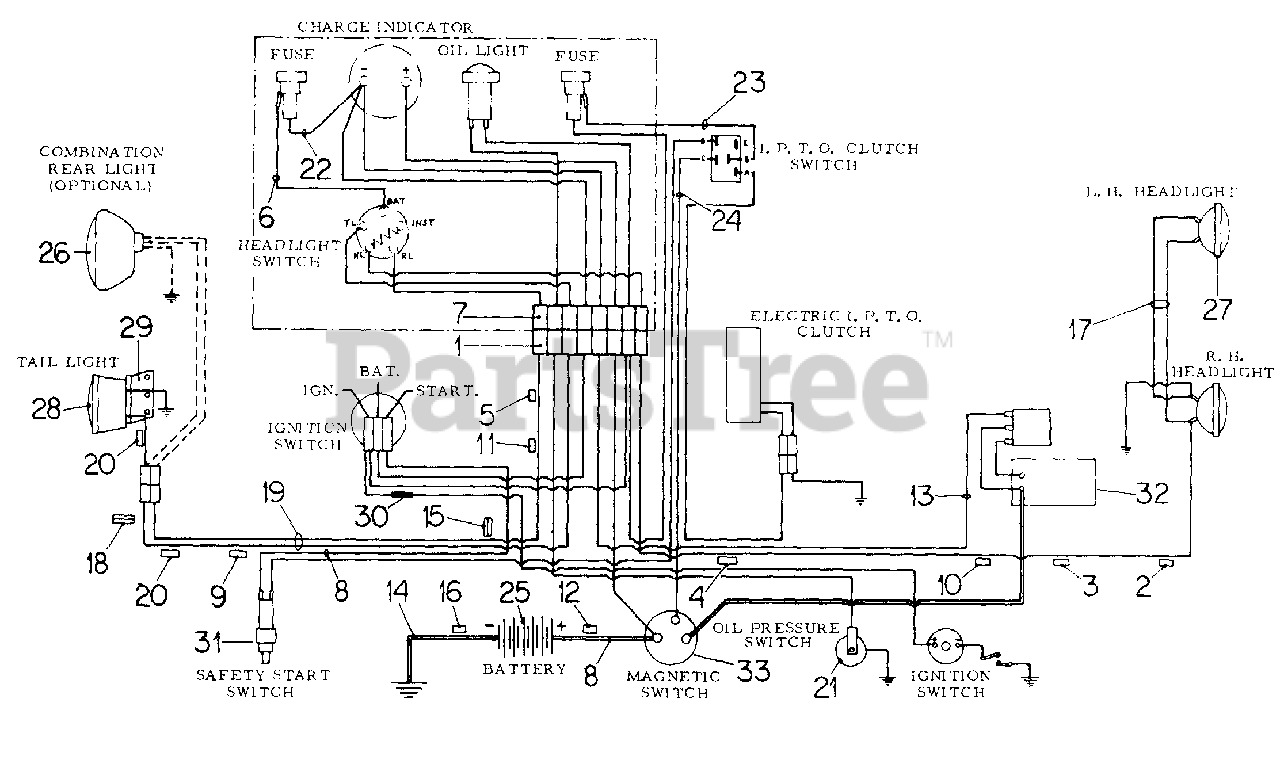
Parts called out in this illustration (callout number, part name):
1	HARNESS, MAIN CABLE
2	CLIP, RAD UPPER RH MTG BOLT
3	CLIP, MOTOR GEN. ADJ. BRACKET
4	CLIP, THROTTLE CABLE
5	CLIP, CABLE
6	CABLE, LT SWITCH TO FUSE
7	CABLE, INSTRUMENT PANEL
8	CABLE, BATTERY TO MAGNETIC SWITCH
9	CLIP, CABLE LH REAR FRAME CHANNEL
10	CLIP, CABLE WATER OUTLET
11	CLIP, CABLE FIREWAIL
13	CABLE, MAGNETIC SWITCH TO GENERATOR
13	CABLE, MAGNETIC SWITCH TO CRANKING MOTOR
14	CABLE, BATTERY TO GROUND
15	GROMMET, RUBBER IN PEDESTAL LH SIDE
16	CLIP, BATTERY CABLE
17	CABLE, HEADLIGHT GROUND
18	GROMMET RUBBER TAIL LIGHT
19	CABLE, TAIL LIGHT
20	CLIP
21	TERMINAL, OIL PRESSURE SWITCH
22	CABLE, CHARGE INDICATOR TO FUSE
23	CABLE, CLUTCH SWITCH -B- TO FUSE
24	CONNECTOR, CABLE
25	BATTERY, 12 VOLT
26	LIGHT, SEALED BEAM HEAD
27	RING, HEADLIGHT
28	LIGHT ASSY, TAIL 12 V
30	RESISTOR -25 OHM
31	SWITCH, NEUTRAL STARTING
32	MOTOR ASSY, CRANKING; IH-131174-C91
33	SWITCH, MAGNETIC
